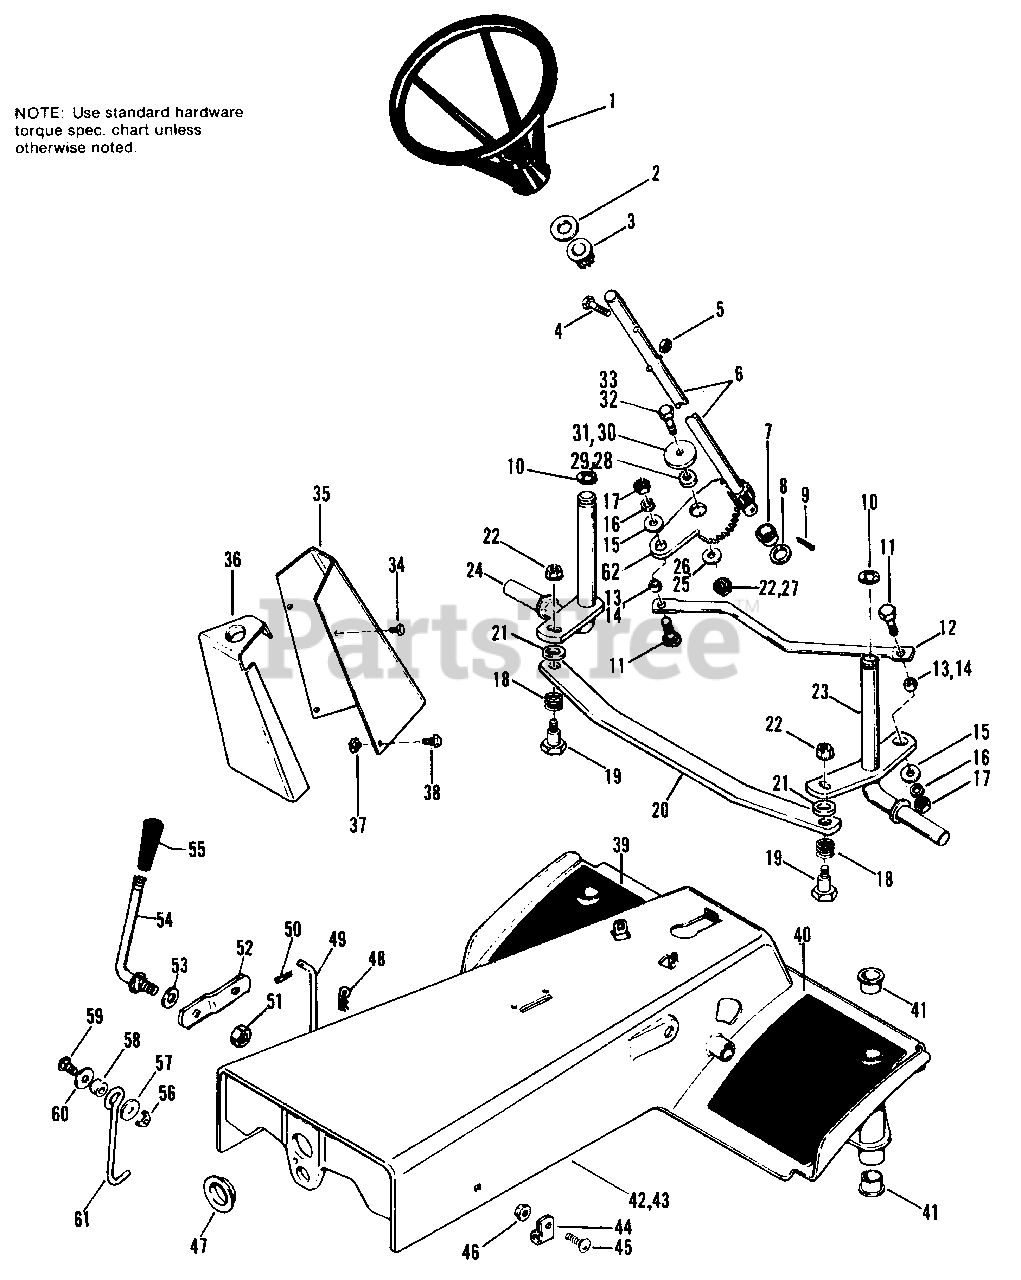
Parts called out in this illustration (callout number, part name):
1	WHEEL, Steering
4	CAPSCREW, Hex Hd., 5/16-18 x 1-1/4
5	LOCKNUT, Hex, 5/16-18
6	SHAFT ASSY., Steering
9	PIN, Cotter, 1/8 x 1-1/4
10	RlNG, Retaining
11	CAPSCREW, Hex Hd., 3/8-16 x 1-1/4
12	LINK, Drag
13	BUSHING (Used on 990963)
14	BUSHING
15	WASHER, Plain, 5/16
16	LOCKWASHER, 3/8
17	NUT, Hex, Full, 3/8-16
19	BOLT, Shoulder
21	WASHER, Plain, 5/16
22	NUT, Flange, 3/8-16 (Qty. 2 used on 1690012)
23	SPINDLE, R.H.
24	SPINDLE, L.H.
25	WASHER (Used on 990963)
26	WASHER
27	NUT, Flange, 7/16-14
28	BUSHING
29	BUSHING
30	WASHER (Used on 990963)
31	WASHER
32	CAPSCREW, Hex Hd., 3/8-16 x 1-1/4 (Used on 990963)
33	CAPSCREW, Hex Hd., 7/16-14 x 1-1/4
34	SCREW, Self Tapping, #10 x 1/2
35	SUPPORT, Steering
36	PANEL, Rear
37	NUT, Retainer
38	SCREW, Hex, Whizlock, Flange, 1/4-20 x 3/4
39	PAD, Foot, L.H.
40	PAD, Foot, R.H.
42	FRAME ASSY., Front
43	FRAME ASSY., Front
44	CLAMP
45	BOLT, Carriage, 5/16-18 x 1/2
46	NUT, Flange, 5/16-18
47	BUSHING, Pivot
48	CLIP, Hair Pin
49	ROD
50	PIN, Cotter, 3/32 x 5/8
51	NUT, Flange, 3/8-16
52	ARM, Lift
53	WASHER
54	HANDLE
55	KNOB
56	NUT, Flange, 5/16-18 (Used on 990963)
57	WASHER (Used on 990963)
58	SPACER (Used on 9990963)
59	BOLT, Carriage, 5/16-18 x 1 (Used on 990963)
60	WASHER (Used on 990963)
61	HOOK (Used on 990963)
62	GEAR, Steering
